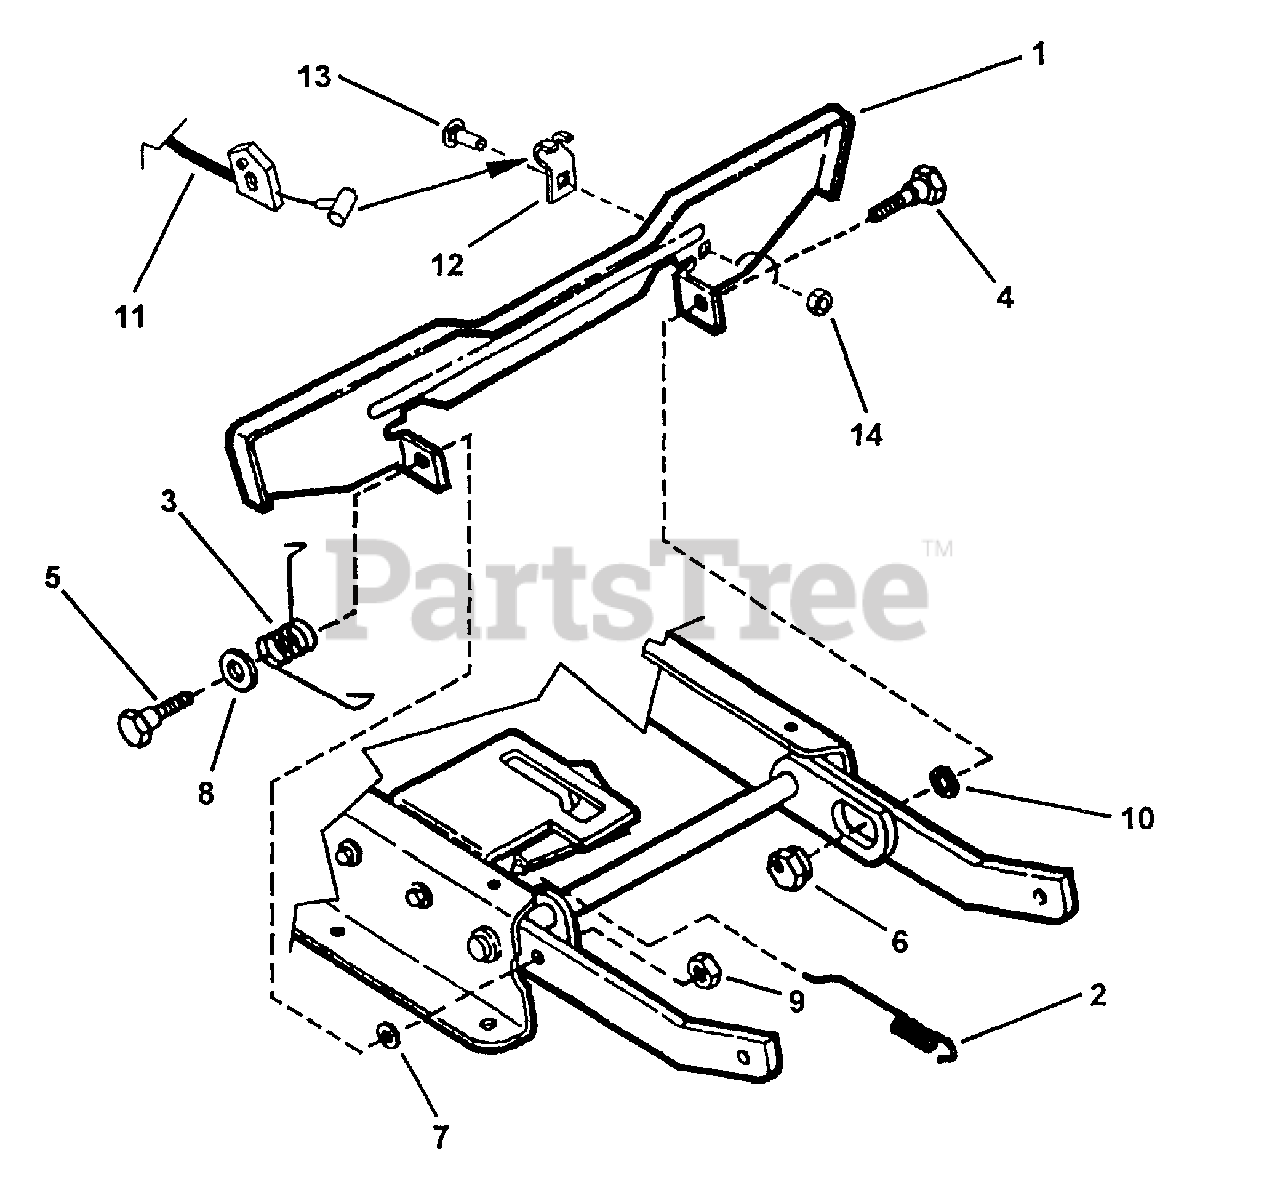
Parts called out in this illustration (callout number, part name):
1	PEDAL, Blade Stop Control
2	SPRING, Latching
3	SPRING, Pedal
4	BOLT, 3/8-24 x 3/4" Shoulder
5	BOLT, 3/8-24 x 9/16" Shoulder
6	ECCENTRIC, Leveling
7	WASHER, 3/8" Flat
8	WASHER, 1/2" Flat
9	NUT, 3/8-24 Hex Center Lock
10	WASHER, 3/8" Internal Tooth Lock
11	CABLE, No Reverse In Mow
12	CLIP, Cable
13	BOLT, 1/4-20 x 3/4" Square Neck Carriage, Grade 5
14	NUT, 1/4-20 Hex, Grade 5 or B
